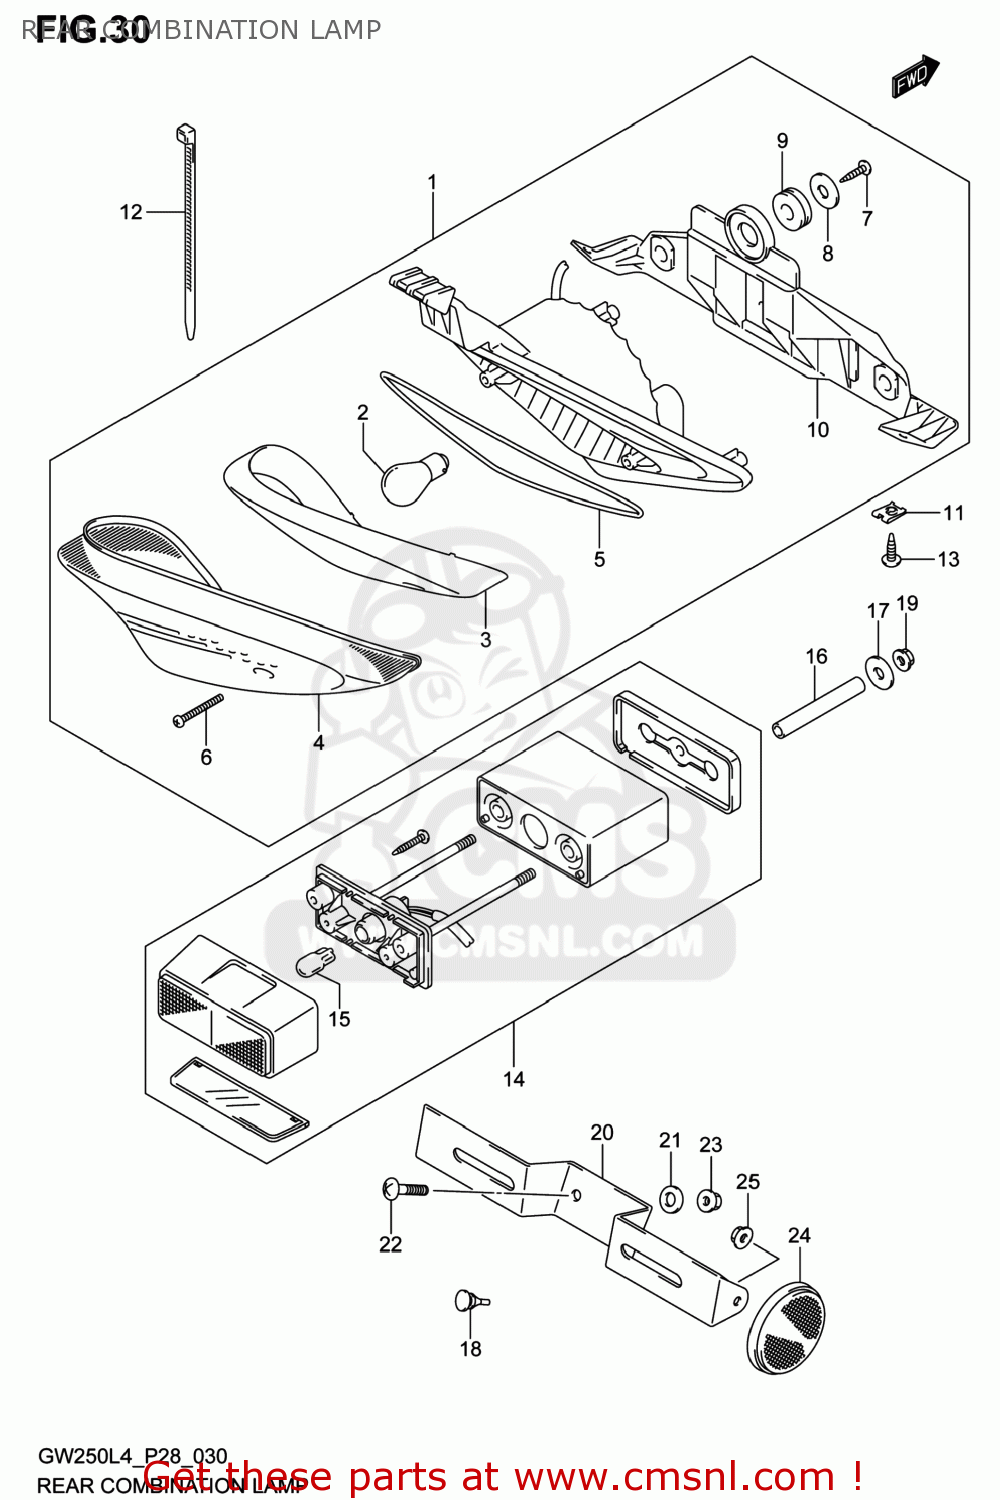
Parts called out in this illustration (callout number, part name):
1	LAMP ASSY,RR COMBINATION
2	BULB(12V21/5W)
3	LENS
4	LENS
5	GASKET (NAS)
6	SCREW
7	SCREW
8	WASHER
9	CUSHION
10	BRACKET
11	NUT,HEADLAMP
12	CLAMP,RR COMBINATION
13	SCREW
14	LAMP ASSY,LICENSE
15	BULB(12V5W)
16	SPACER,LICENSE LAMP
17	WASHER(6.5X20X1.2)
18	CUSHION,LICENSE PLATE
19	NUT
20	BRACKET,LICENSE PLATE
21	WASHER(6.5X16X1.2)
22	SCREW
23	NUT
24	REFLECTOR ASSY,RR SIDE
25	NUT
